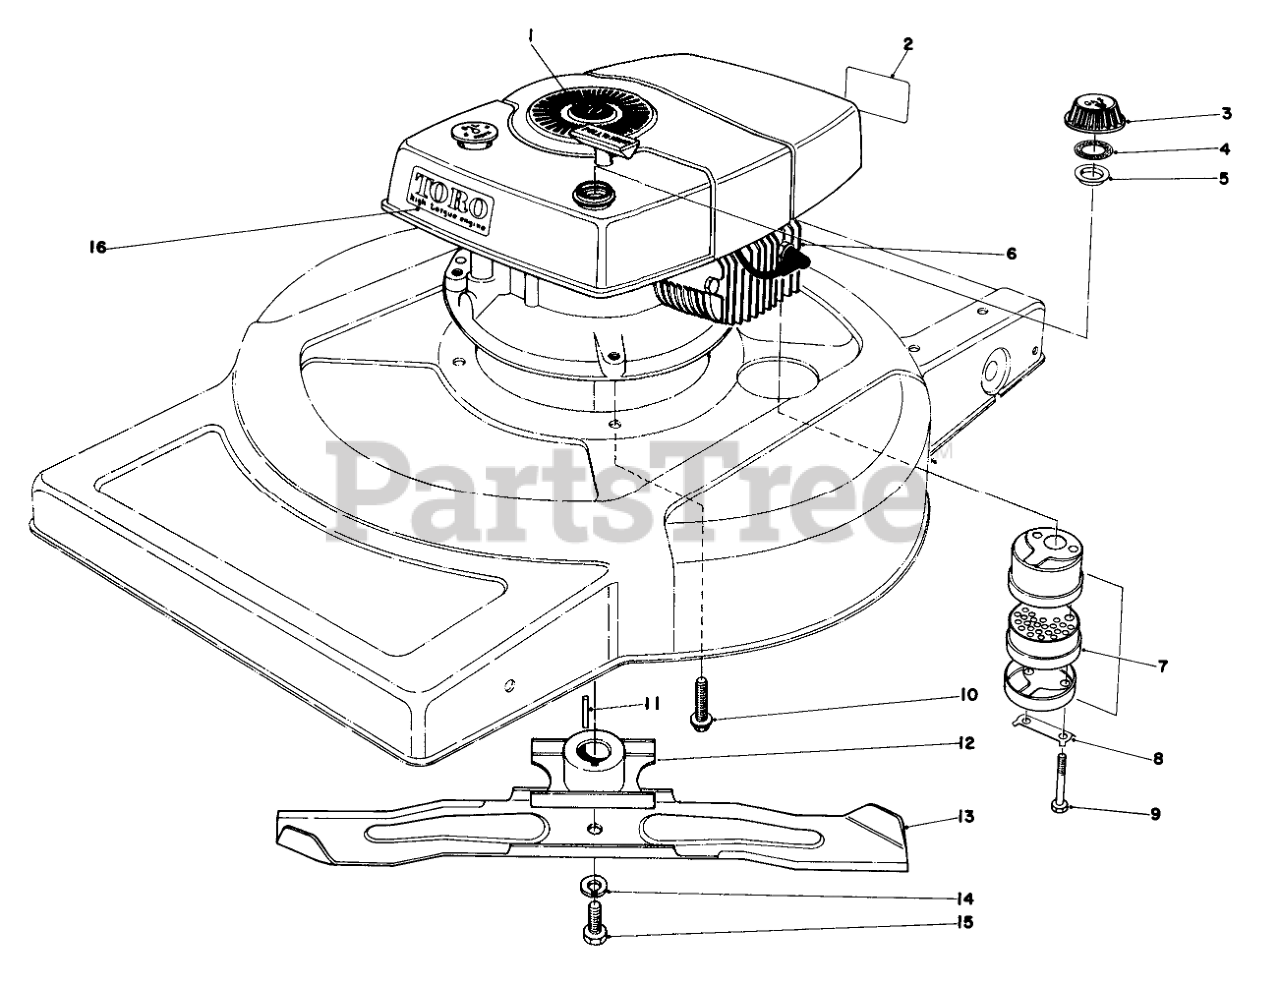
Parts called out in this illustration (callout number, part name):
1	Plug Button
2	Decal-Maintenan
3	Gas Cap (Incl. Ref. #4 & 5)
4	GASKET
5	GAS CAP BAFFLE
6	Engine
7	Muffler Assembly (Incl. Ref. #8 & 9)
8	CLIP - LOCKING
9	SCREW-HH
10	SCREW-HWHTF
11	KEY-SQUARE
12	BLADE RETAINER WA(BLACK)
13	Blade
14	WASHER-LOCK
15	BLADE SCREW
16	High Torque
